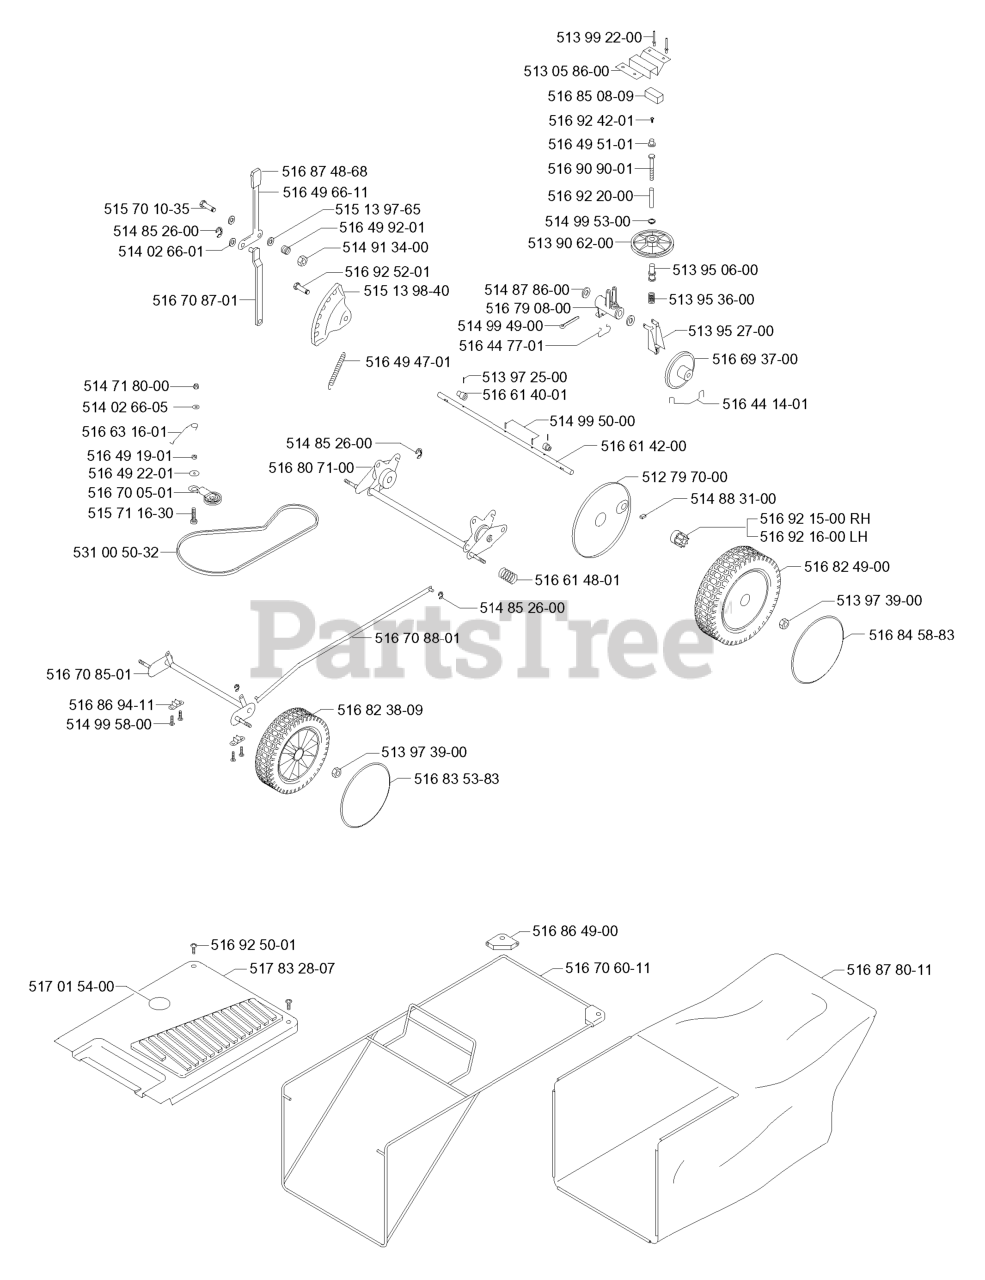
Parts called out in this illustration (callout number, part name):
9	WASHER BRB 8.4X17
10	LOCKNUT M8
18	SCREW
20	LOCKNUT M8
22	REPL BY 725 24 49-51
25	LOCKNUT M5
30	LOCKNUT M8
31	SPRING
34	EXPANSION TANK K664
35	BOLT FLANGE - M6X20
36	WASHER - 26X6.5X1.6
46	Screw M10x25
49	WASHER BRB 8.4X17
50	LOCKNUT M8
